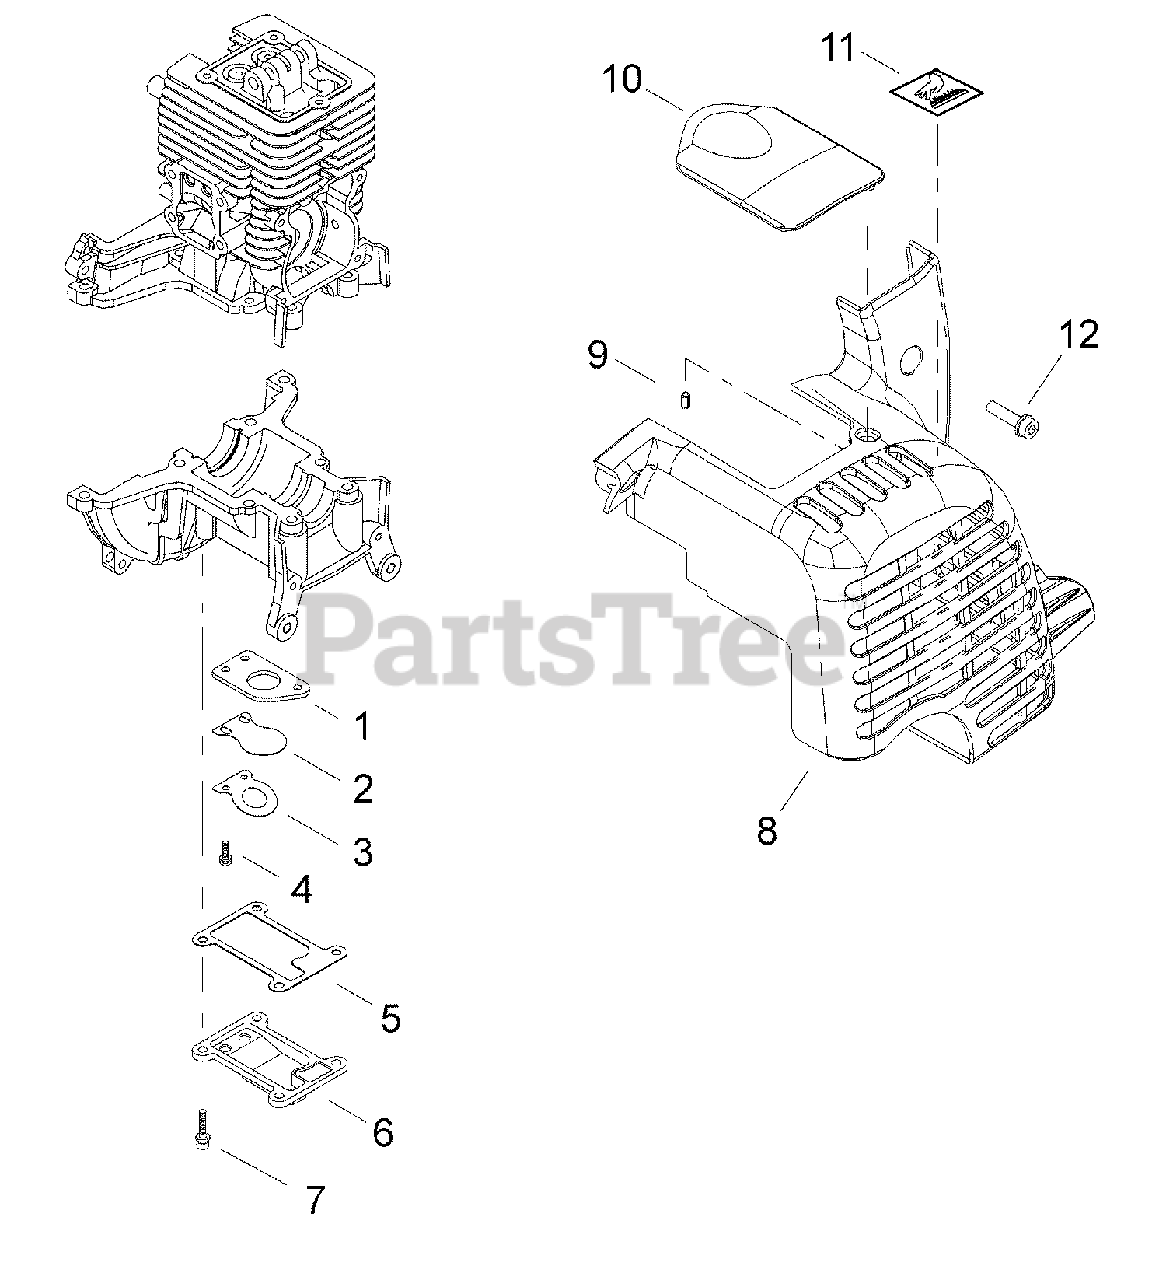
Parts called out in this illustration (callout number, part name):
1	PLATE, REED BACKING
2	VALVE, REED
3	STOP, REED VALVE
4	SCREW - 3X10
5	GASKET, REED VALVE
6	COVER, REED VALVE
7	SCREW - 4X14
8	COVER, ENGINE
9	PIN - 4X8
10	COVER, SPARK PLUG
11	LABEL - CAUTION
12	BOLT - 5X20
